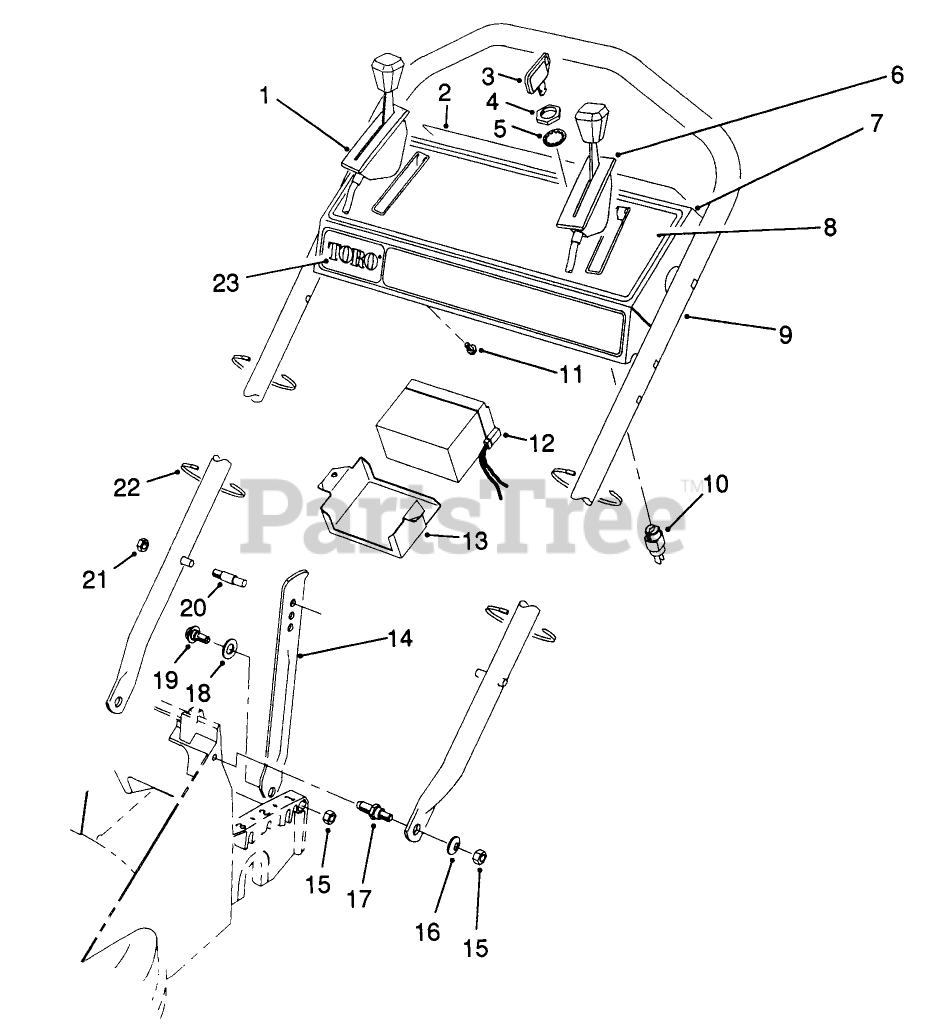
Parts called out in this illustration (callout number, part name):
3	KEY-IGNITION
4	NUT-HH
5	WASHER-LOCK
10	STARTER SWITCH ASM
11	SCREW-HWHTF
12	BATTERY ASSEMBLY,WET
15	NUT-LOCK, NI
16	WASHER-PLAIN
19	SCREW-SHOULDER
20	HANDLE PIN
21	NUT-LOCK, NI
22	TIE-CABLE
